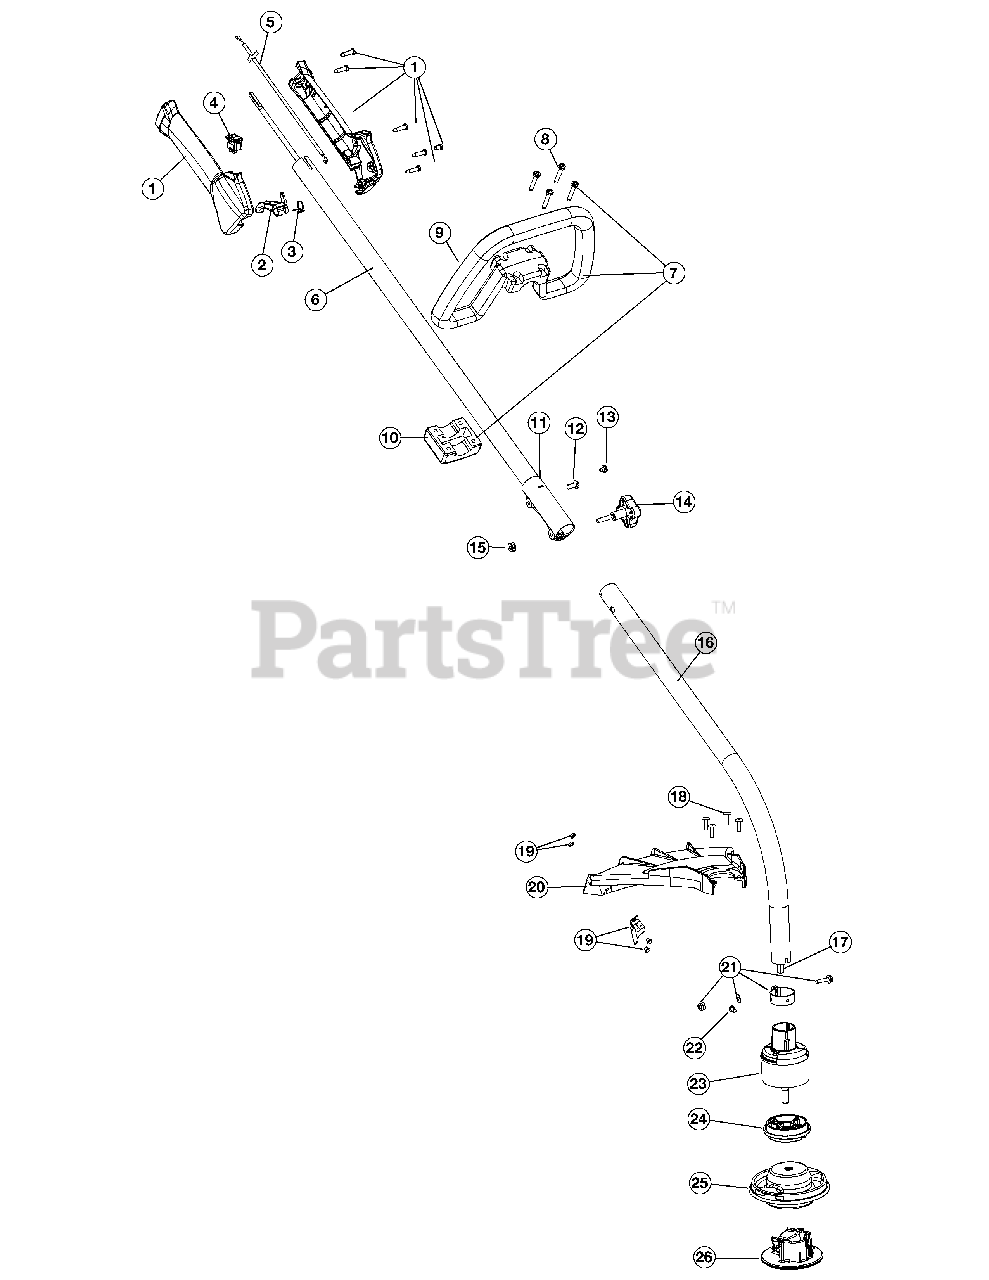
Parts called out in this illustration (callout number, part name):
1	Throttle Housing Assembly (includes 2-4)
2	Throttle Trigger
3	Throttle Trigger Spring
4	Switch Assembly
5	Throttle Cable Assembly
6	Upper Drive Shaft Housing
7	Deluxe D-Handle Assembly (includes 8-10)
9	D-Handle
10	D-Handle Base
11	Click Link Coupler (includes 12-15)
14	Adjustment Knob (includes 15)
15	Nut
16	Lower Drive Shaft Housing
17	Lower Flexible Drive Shaft
18	Shield Mount Hardware
19	Blade Assembly
20	Shield Assembly (includes 19)
21	Lower Clamp Assembly (includes 22)
22	Anti-Rotation Screw
23	Bushing Housing Assembly
24	Adapter
25	Cutting Head Assembly
26	Cutting Head Cap
